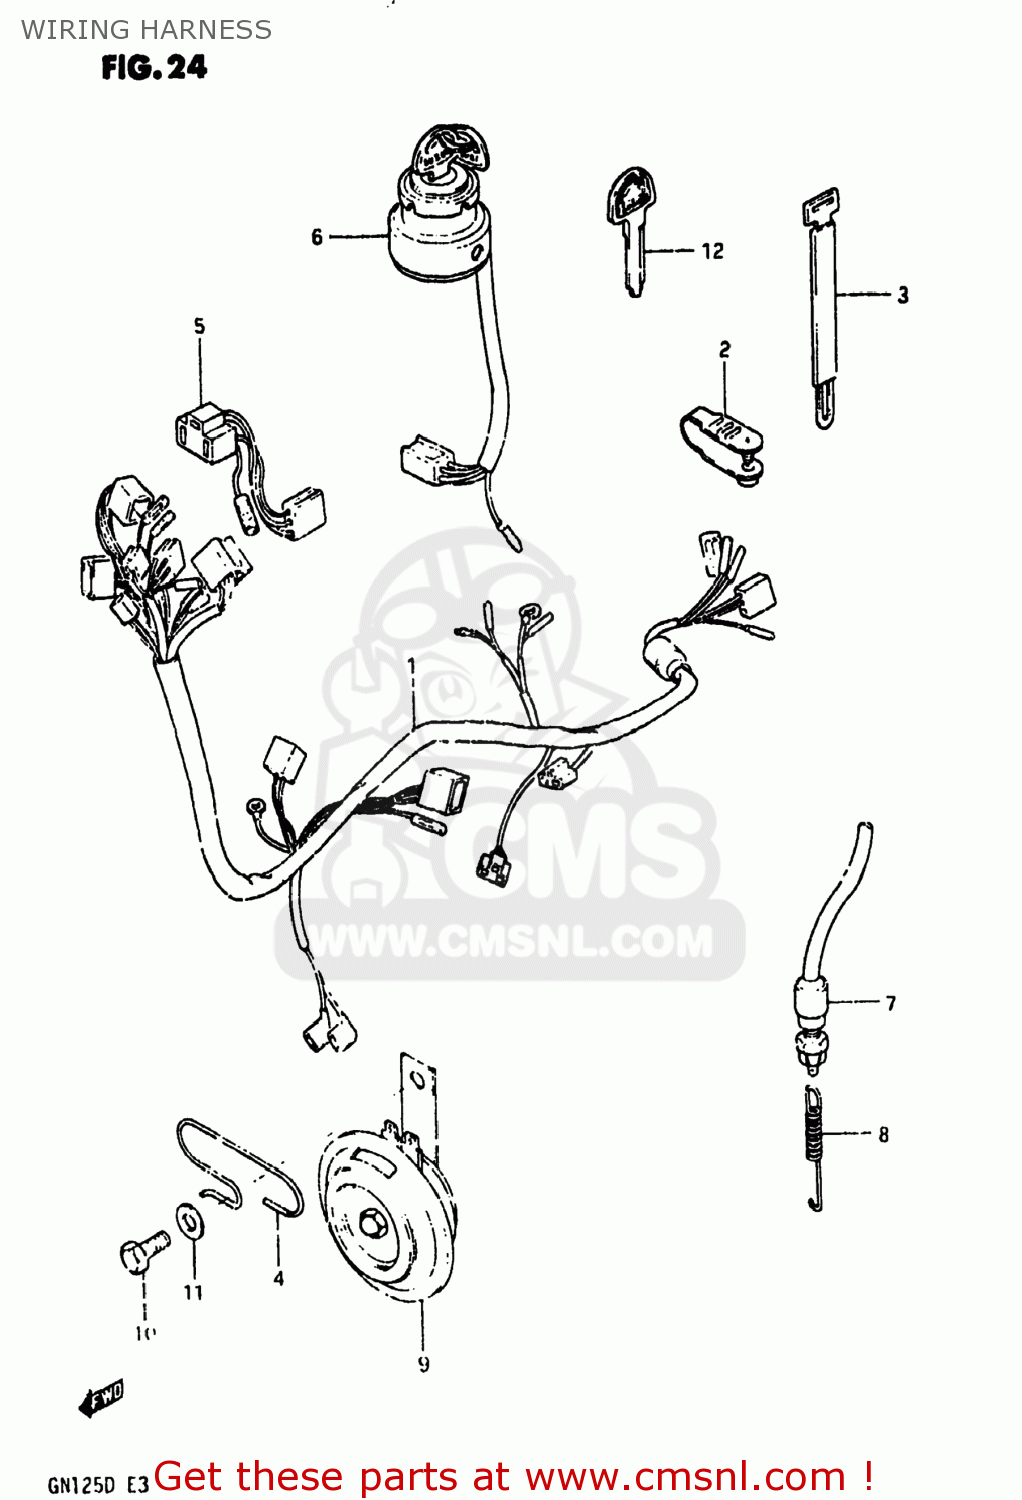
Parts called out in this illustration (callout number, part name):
1	HARNESS,WIRING
2	CLAMP,L:88
3	CLAMP
4	CLAMP,WIRING HARNESS
5	LEAD WIRE,HEADLAMP
6	SWITCH ASSEMBLY,IGNITION
7	SWITCH ASSEMBLY,STOP LAMP
8	SPRING
9	HORN ASSEMBLY
10	BOLT
11	WASHER
12	KEY,BLANK
